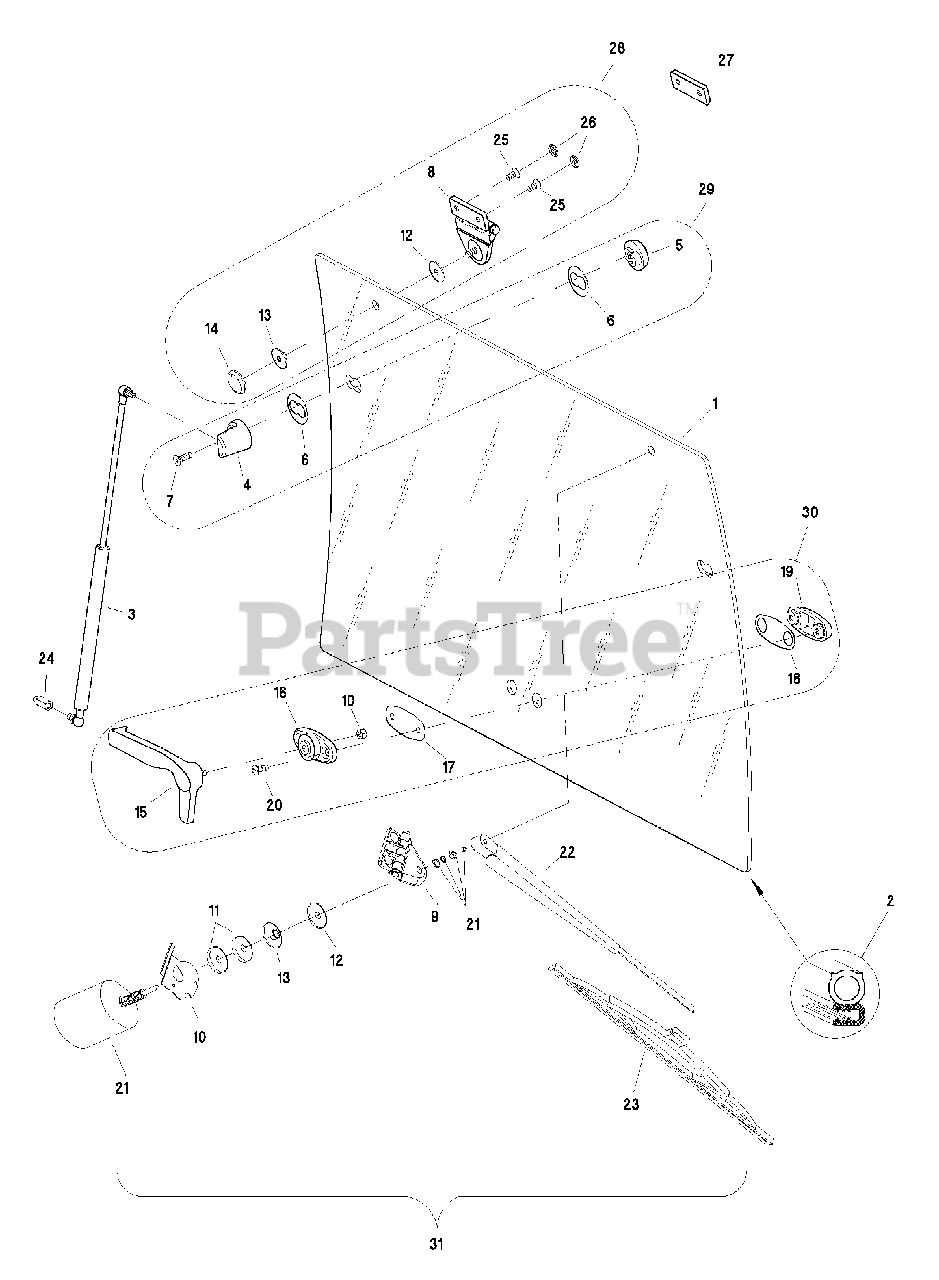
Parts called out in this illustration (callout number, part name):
2	PROFILE SEALING, 11 ft. 2 in.
3	GASLIFT, 500MM/200N
4	BEARING, Inner Gaslift
5	BEARING, Outer Gaslift
6	WASHER, Rubber
8	PVC HINGE, Complete
9	HINGE, Complete, Drilled
10	Fuse, Wipermotor
11	WASHER, Plastic
12	WASHER, Rubber
13	WASHER, Rubber with Socket
14	WASHER, with Bushing, M8
15	HANDLE, Lock
16	SOCKET, Inner Handle
19	SOCKET, Outer Handle
21	MOTOR, Wiper 85/12V, (Includes washers)
22	ARM, Wiper 300-400
24	GASLIFT SOCKET
27	INNER BRACKET, Hinge
28	SET HINGE, (Includes Ref. 6 - 11)
29	SET GASSPRING SOCKET, (Includes Ref. 26 - 29)
30	SET LOCKING, (Includes Ref. 13 - 18)
31	WINDSHIELD, Complete (Includes Ref. 2 - 30)
